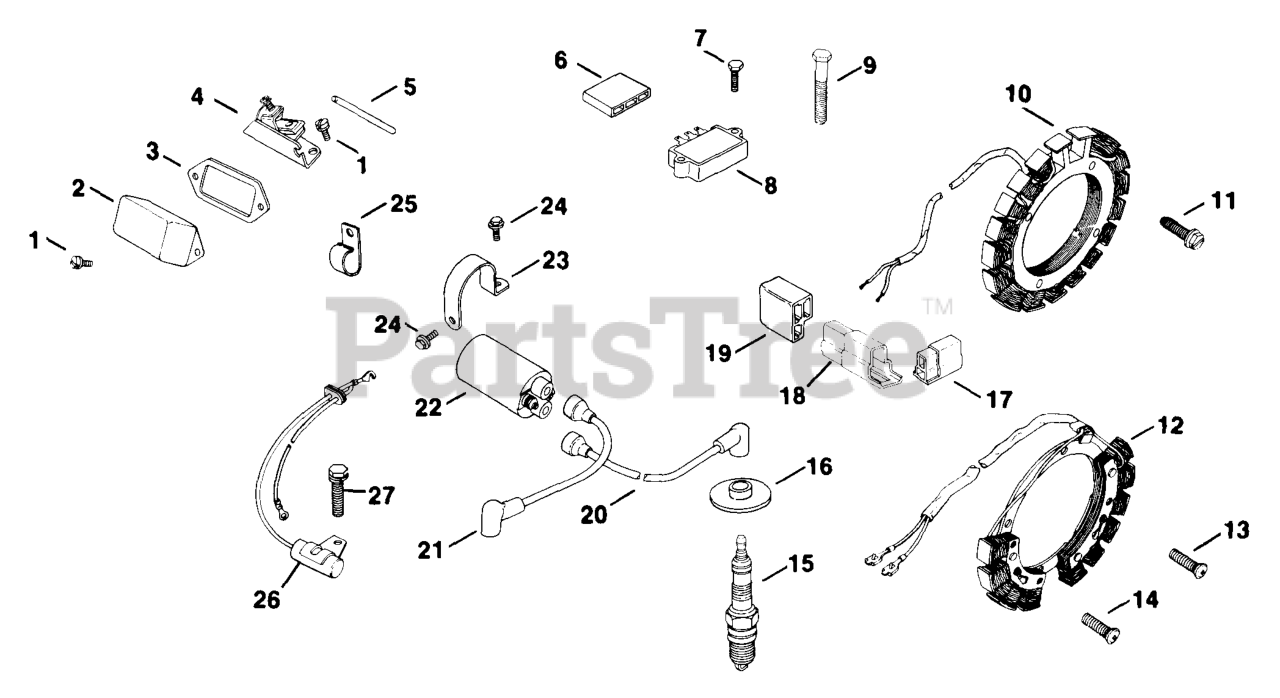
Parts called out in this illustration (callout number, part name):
1	SCREW - DISCONTINUED
2	COVER - (#DSC)
3	GASKET - USE 52 041 11
4	BREAKER - USE 47 150 03
5	ROD - USE 52 411 05
13	Screw, fillister hd. 10-24 x 7/16
14	Screw, fillister hd. 10-24 x 15/16
15	SPARK PLUG - USE 52 132 02
19	CONNECTOR
20	KIT - USE 52 755 49
21	KIT - USE 52 755 49
22	COIL - USE 52 145 02
23	STRAP - USE 52 445 03
24	Screw, tapping 1/4-20 x 7/16
26	KIT, CONDENSER - DISCONTINUED
27	Screw, hex. washer hd. 1/4-20 x 3/4
2551807	Lead, coil
